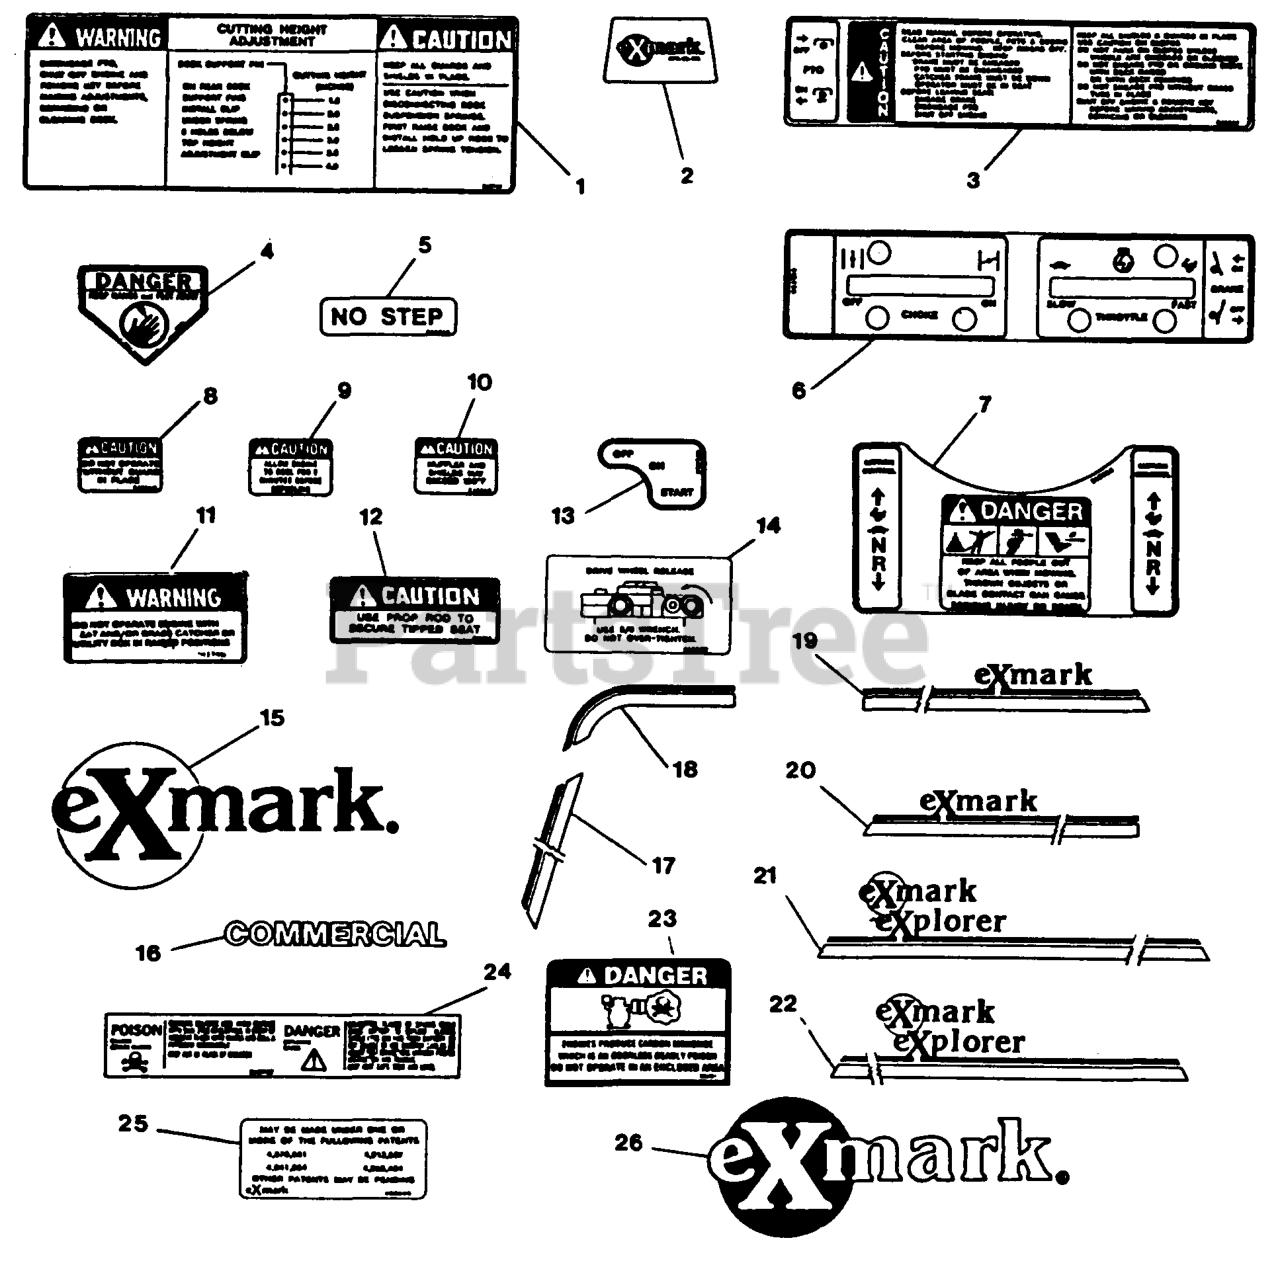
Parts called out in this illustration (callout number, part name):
3	DECAL,FENDER RH
4	DECAL-DANGER
5	DECAL,NO STEP
7	DECAL,CONSOLE
8	DECAL-GUARD
24	DECAL-BATTERY
